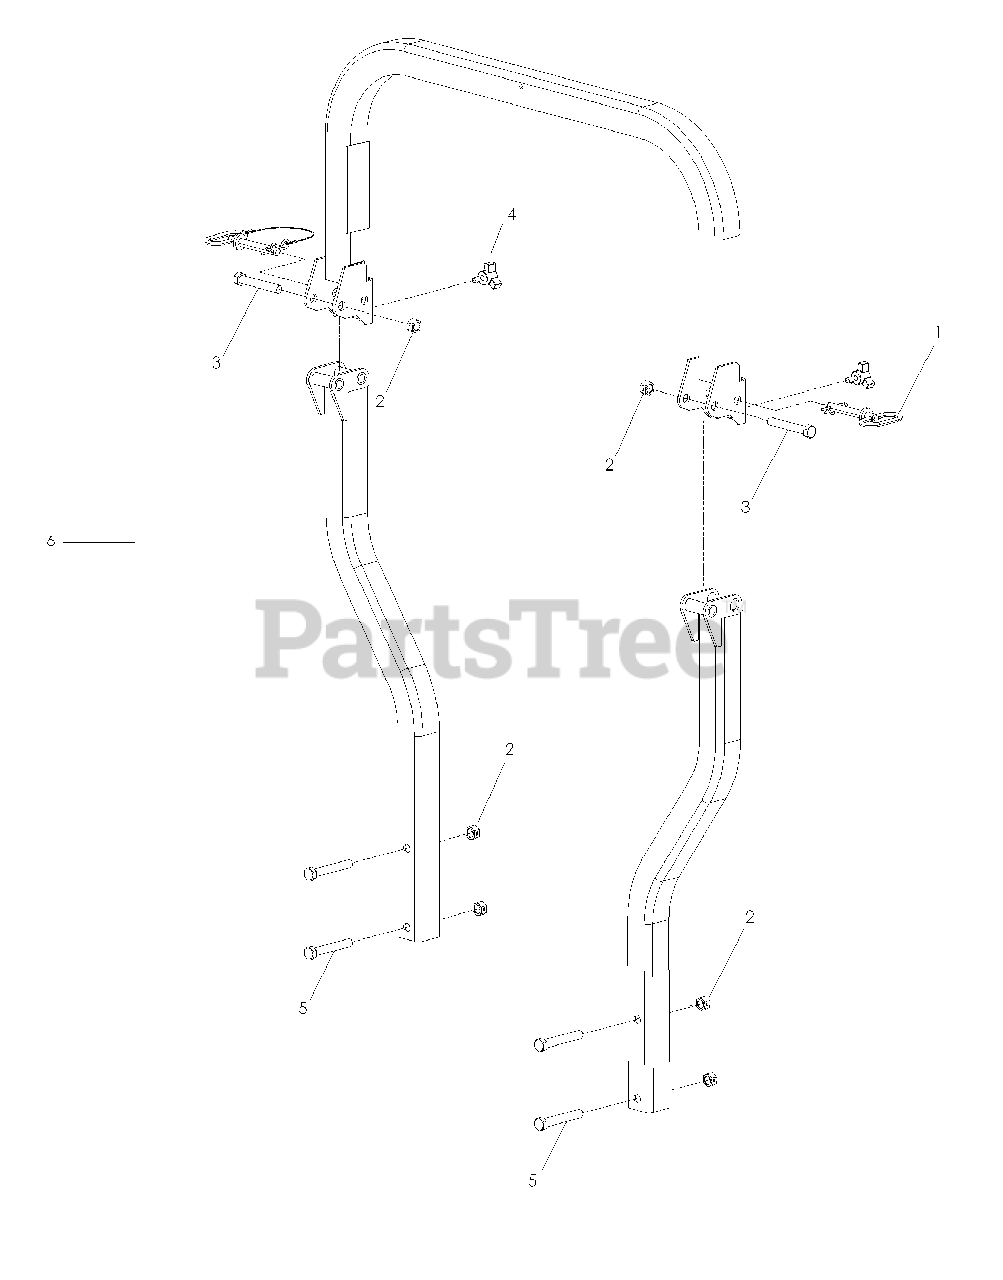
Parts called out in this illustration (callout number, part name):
1	PIN 1/2 W/LANYARD
2	NUT 1/2-13 CENTERLOCK
3	HCS 1/2-13 x 3 1/4
4	KNOB W/STUD
5	HCS 1/2-13 x 4
6	ROPS COMPLETE
